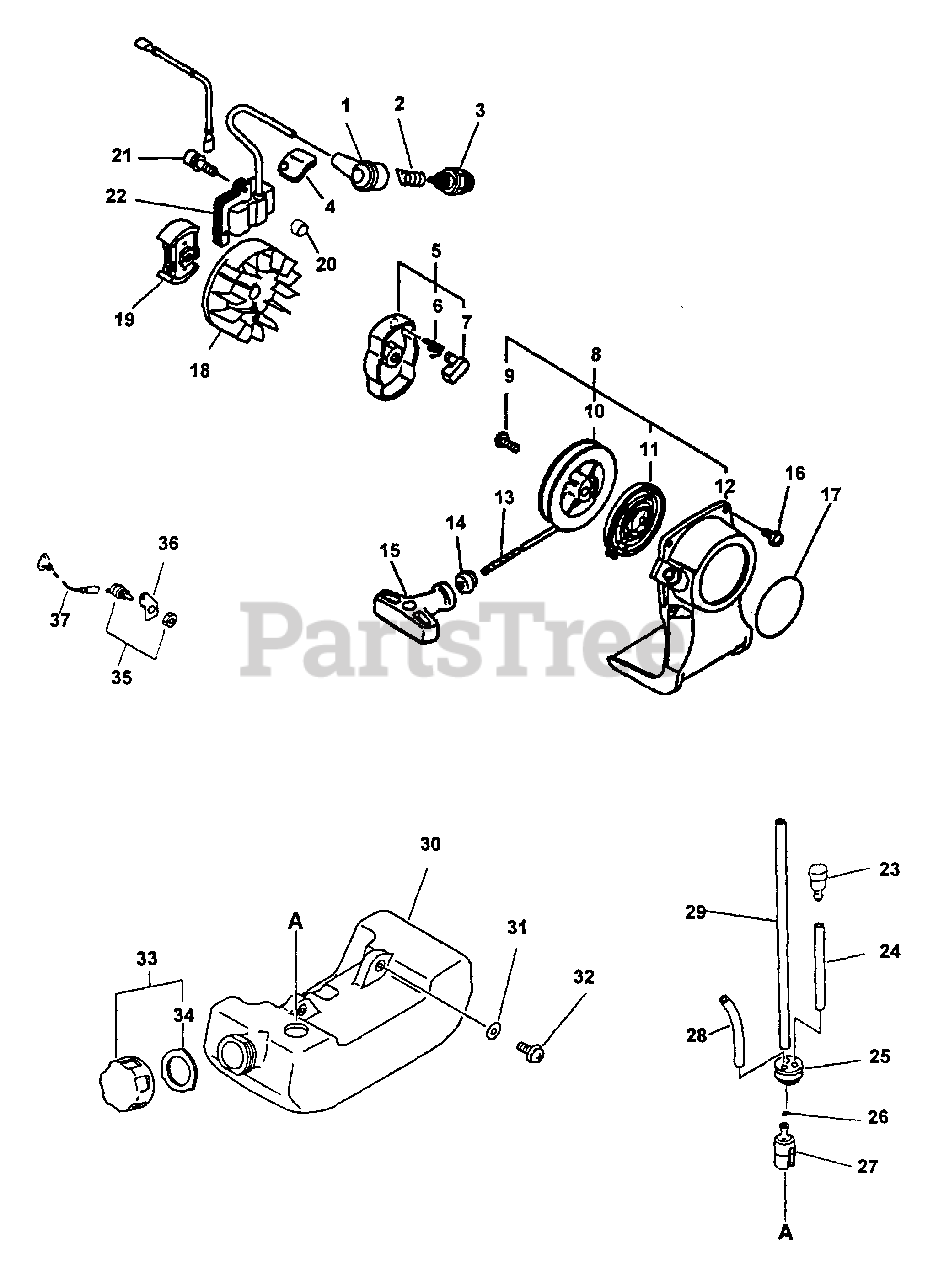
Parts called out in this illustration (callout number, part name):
1	CAP, SPARK PLUG
2	TERMINAL, SPARK PLUG CAP
3	SPARK PLUG -- BPM-7A
4	GROMMET
5	STARTER PAWL ASSY
6	SPRING, RETURN
7	PAWL, STARTER - BLACK
8	STARTER ASSY
10	REEL, ROPE
11	SPRING, REWIND
12	CASE, STARTER - BLUE
13	ROPE, STARTER - 3X1000
14	GUIDE, ROPE
15	GRIP, STARTER
16	SCREW - 4X16
17	LABEL - ECHO
18	FLYWHEEL
19	CLUTCH ASSY
21	SCREW - 4X22
22	COIL, IGNITION
23	VENT, FUEL TANK
24	PIPE - 3X5X70 -- BLACK
25	GROMMET
26	CLIP - 6
27	FILTER, FUEL
28	PIPE - 3X6X90 -- CLEAR
29	PIPE - 3X5X180 -- BLACK
30	TANK, FUEL
31	WASHER - 5
32	SCREW - 5X16
33	CAP ASSY
34	GASKET, CAP
35	IGNITION SWITCH ASSY
36	BRACKET, SWITCH
37	LEAD - GROUND
